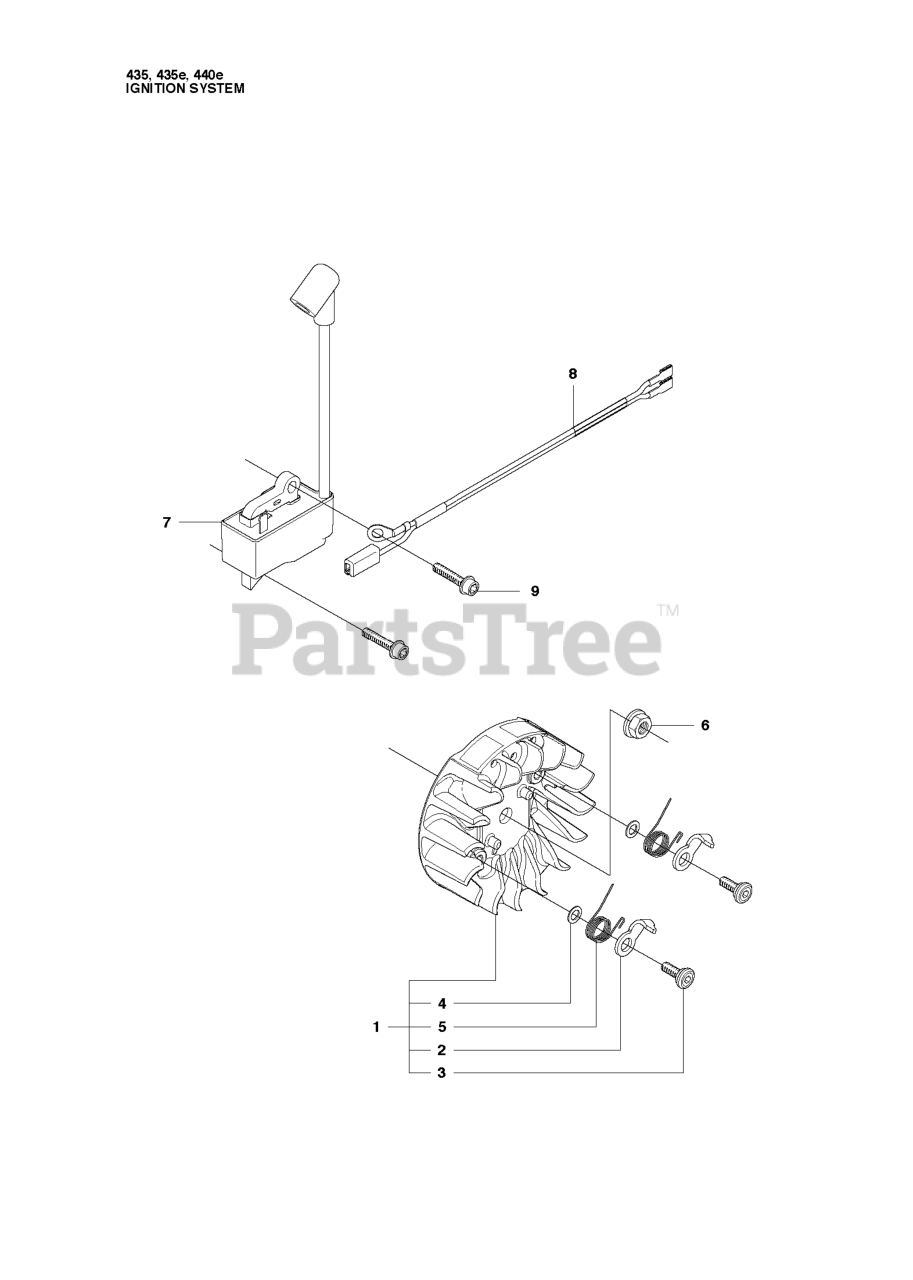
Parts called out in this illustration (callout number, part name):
1	FLYWHEEL ASSY
6	NUT W/ WASHER
7	IGNITION MODULE
8	WIRING ASSY
